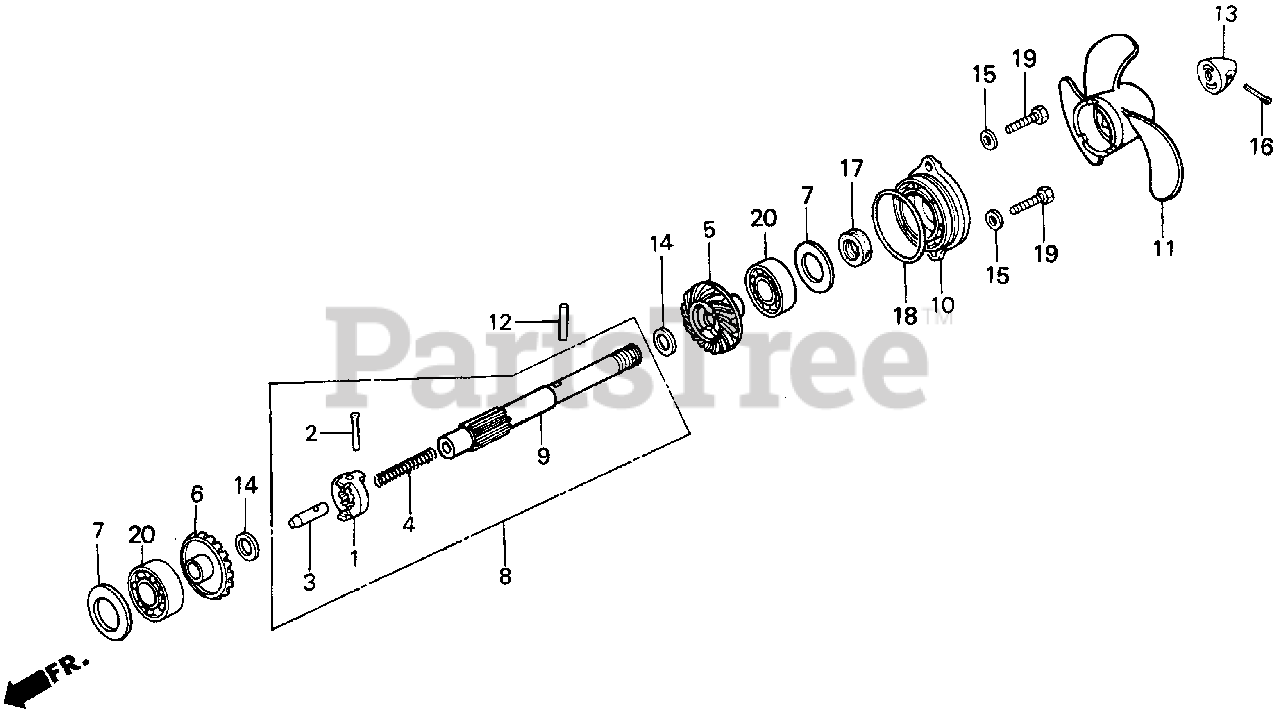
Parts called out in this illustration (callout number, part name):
1	SHIFTER, CLUTCH
2	PIN, SHIFTER (3X26)
3	SLIDER, SHIFT
4	SPRING, SHIFT
5	GEAR, BEVEL (F)
6	GEAR, BEVEL (R)
7	SHIM B, GEAR (0.10MM)
7	SHIM C, GEAR (0.15MM)
8	SHAFT, PROPELLER
9	SHAFT, PROPELLER
10	HOLDER, PROPELLER SHAFT *NH282MU* (OYSTER SILVER METALLIC-U)
11	PROPELLER, THREE-BLADE
11	PROPELLER, THREE-BLADE (200X190) *NH283* (STIN GRAY)
12	PIN, SHEAR
13	CAP, PROPELLER
14	WASHER (13MM)
15	WASHER, PLAIN (6MM)
16	PIN, COTTER
17	SEAL, WATER (13MM) (ARAI)
18	O-RING (52MM)
19	BOLT, HEX. (6X18)
20	BEARING, RADIAL BALL (6004)
